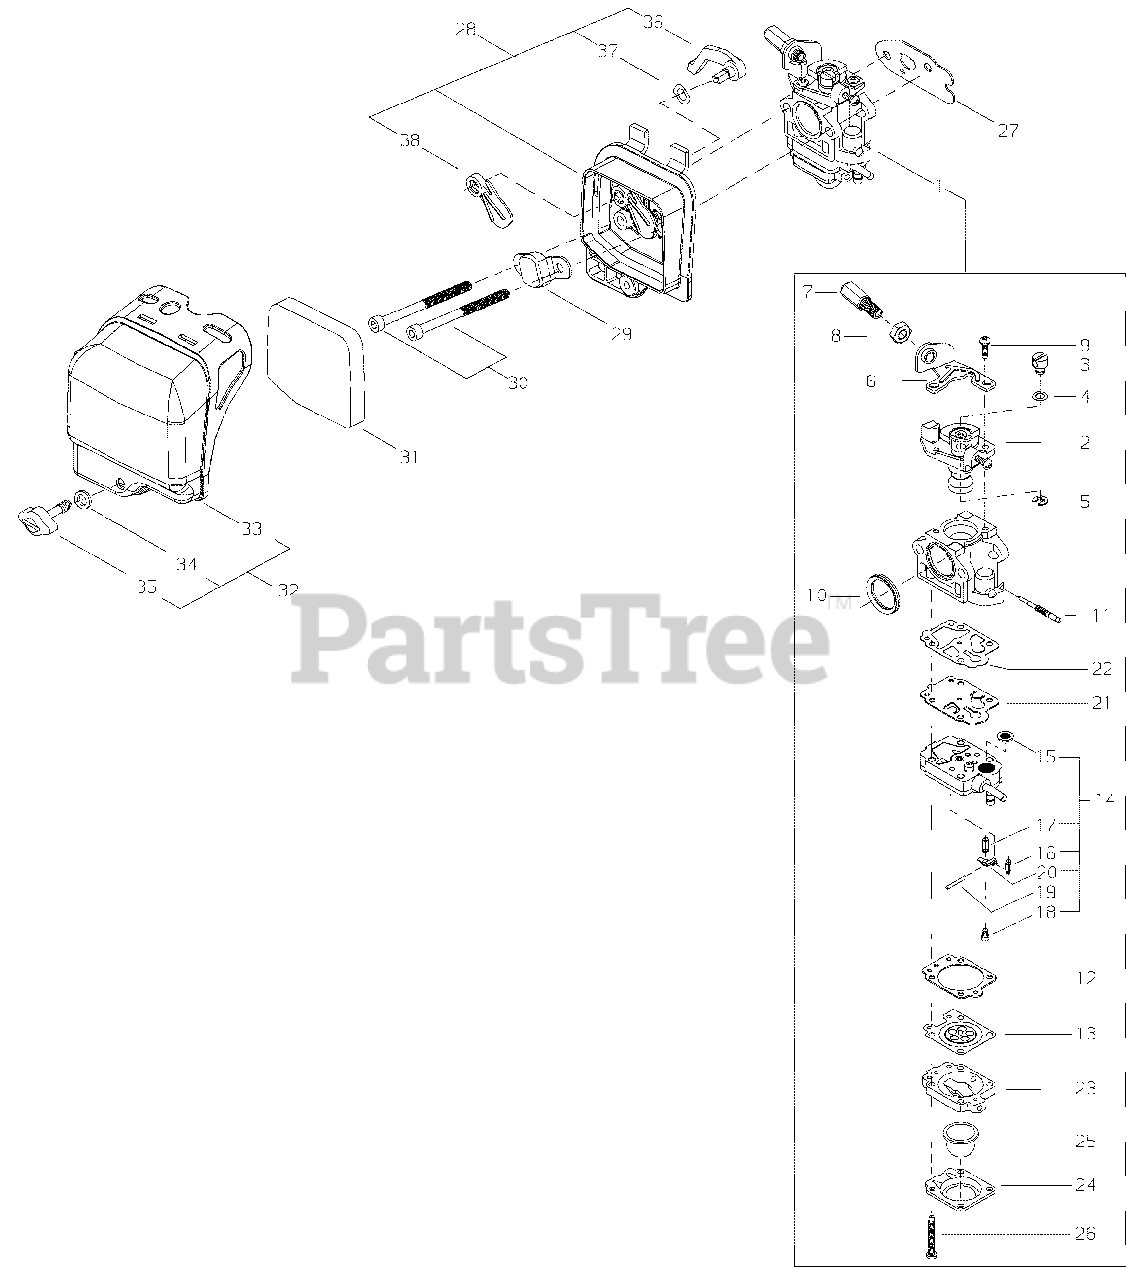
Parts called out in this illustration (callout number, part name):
1	CARBURETOR
2	THROTTLE VALVE ASSY
3	SWIVEL
4	WASHER
5	RING, RETAINING
6	BRACKET, CABLE
7	NUT, CABLE ADJUST
8	NUT
9	SCREW
10	SEAL
11	NEEDLE - HIGH SPEED
12	GASKET, METERING
13	DIAPHRAGM, METERING
14	PUMP BODY ASSY
15	STRAINER
16	VALVE, INLET NEEDLE
17	SPRING, METERING LEVER
18	SCREW, METERING LEVER PIN
19	PIN, METERING LEVER
20	LEVER, METERING
21	DIAPHRAGM, PUMP
22	GASKET, PUMP
23	BASE, PURGE
24	RETAINER, PURGE BULB
25	BULB, PURGE
26	SCREW, PUMP COVER
27	GASKET, INTAKE
28	AIR FILTER CASE ASSY
29	PLATE, PREVENT
30	SCREW - 5X60
31	FILTER, AIR
32	AIR FILTER COVER ASSY
33	COVER, AIR FILTER
34	WASHER - VINYL
35	THUMBSCREW
36	LEVER, CHOKE
37	WASHER - SPRING
38	PLATE, CHOKE
